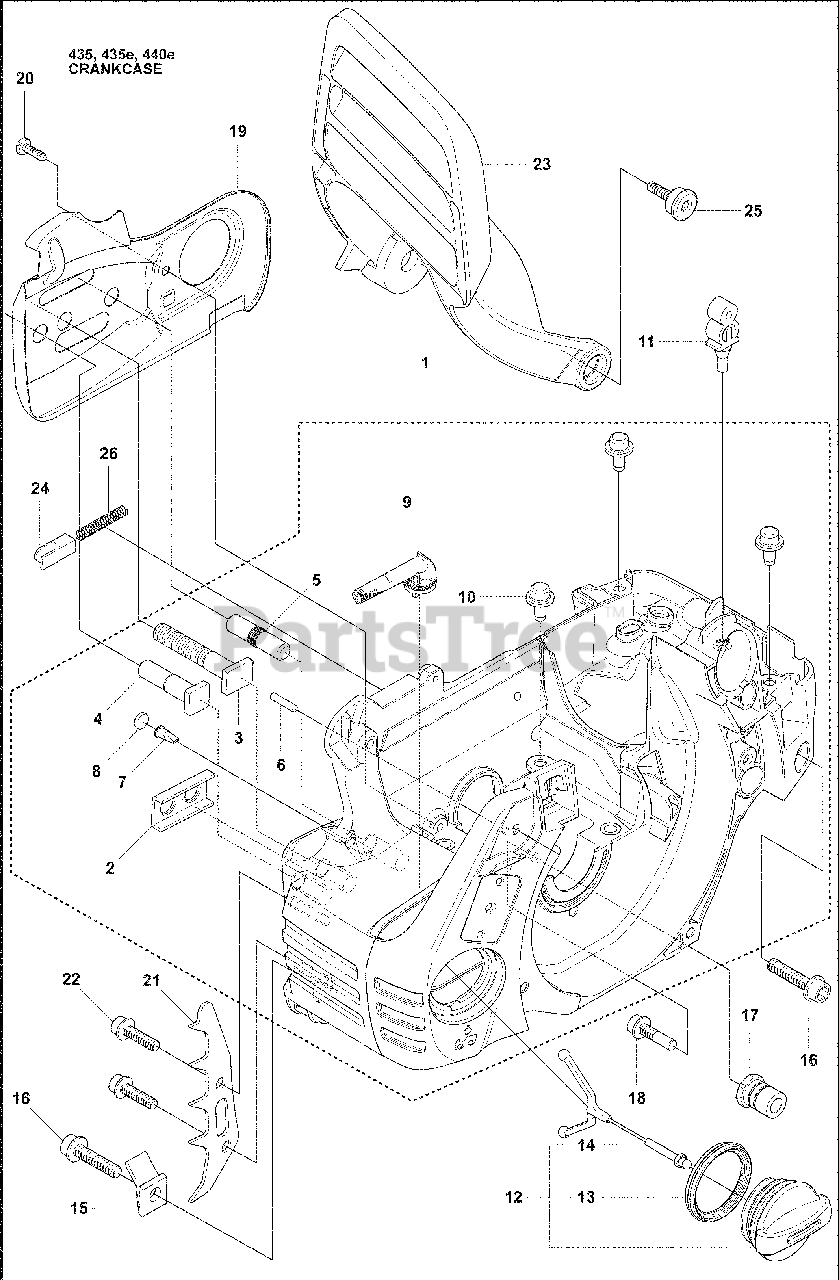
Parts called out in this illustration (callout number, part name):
1	Crankcase Assembly
2	Stiffening Plate
3	Bar Bolt
4	Bar Bolt, X2
5	Bar Bolt
6	Pin
7	Valve Check, Duckbill
8	Sintered Filter, Bronze
9	Oil Screen
10	GUIDE PEN
11	Support
12	Fuel Tank Cap Assembly, Grey
13	Sealing Gasket
14	Holder
15	Chain Catcher
16	Screw, 3 X 25 IHSCFT
17	Lateral Support
18	Screw, Ihscft
19	Chain Guide Plate
20	Screw
21	Spike, Inner
22	Screw
23	Hand Guard
24	Catch
25	Screw
26	Lock Spring
